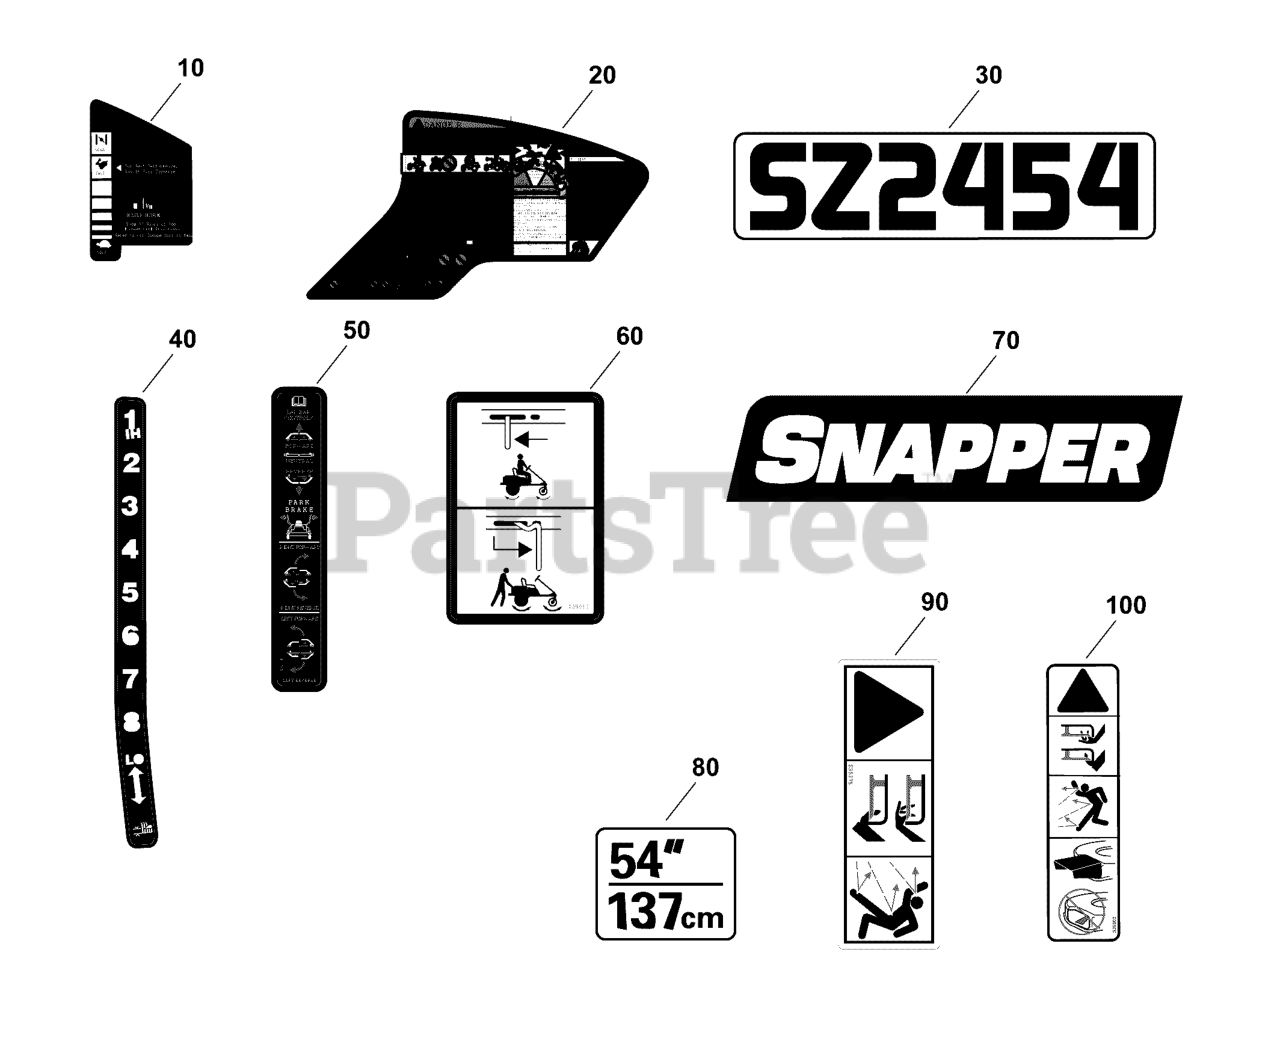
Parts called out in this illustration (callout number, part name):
10	DECAL, Speed Shift
20	DECAL, Starting Instructions
30	DECAL, SZ2454
40	DECAL, Snapper Logo
50	DECAL, Transmission Release
60	DECAL, Lap Bar Controls
70	DECAL, Cutting Height
80	DECAL, Mower Width 54IN/134CM
90	DECAL, Danger
100	DECAL, Danger
